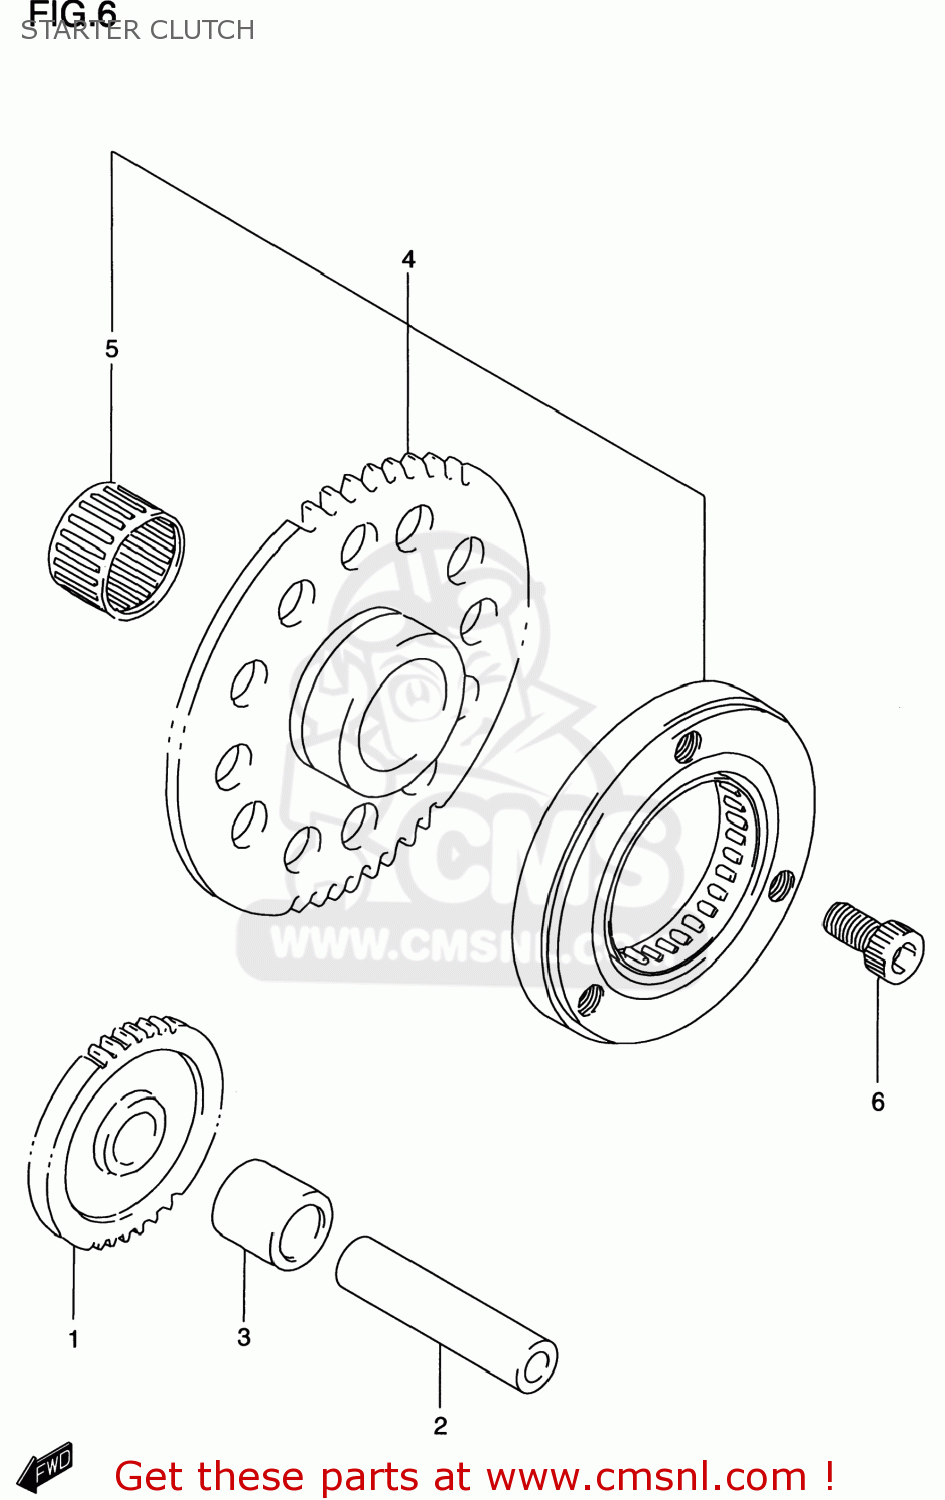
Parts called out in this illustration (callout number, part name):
1	GEAR,STARTER,IDLE
2	PIN(7.4X13X56)
3	SPACER(13X19X19)
4	CLUTCH SET,STARTER
5	BEARING(22X28X16)
6	BOLT
